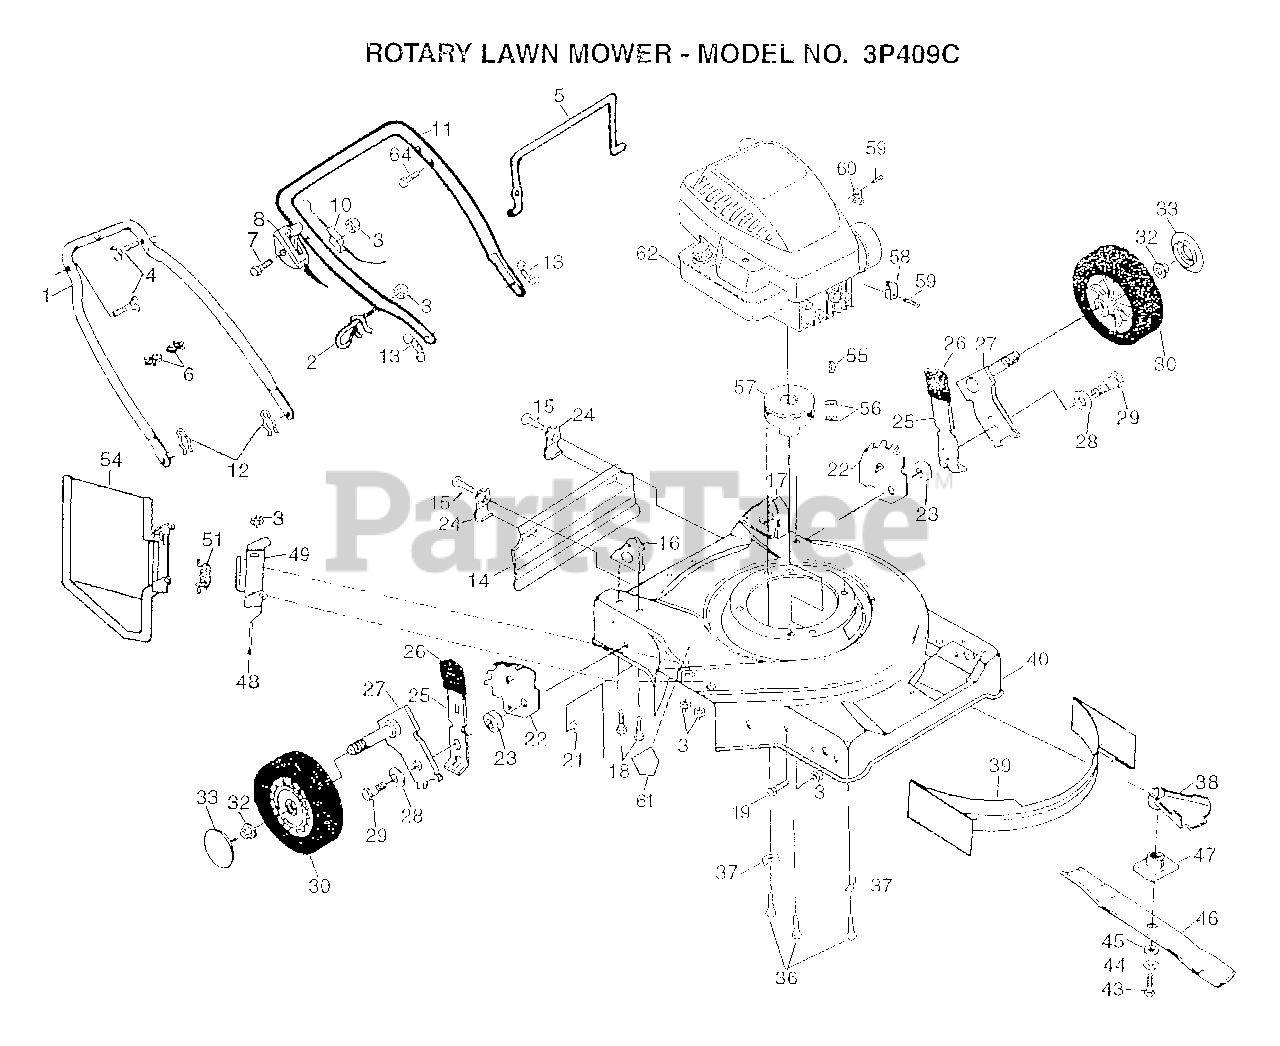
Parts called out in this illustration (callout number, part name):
1	HANDLE LOWER
2	ROPE GUIDE
4	BOLT.HANDLE.LM
5	BAIL.CNTRL.STD.BL
7	SCREW.HXHD.WASH.
8	CONTROL THROTTLE
10	"CABLE,ENG ZONE CO"
12	HAIRPIN COTTER
13	"NUT,WING PM"
14	SKIRT.REAR.FGD.22
15	TAPPING SCREW
16	HDLE BRKT ASSY.RH
17	HDLE BRKT ASSY LH
18	SCREW 5/16-18X3/4
19	SCREW
21	LOCKNUT PM
22	BRACKET.ADJ.9POS.
23	SPACER.HEIGHT.ADJ
24	"BRKT,DEFL PM"
25	SPRING SELECTOR
26	KNOB PM
27	ARM.AXLE.ASM.BZP.
28	"WASHER, BELLEVIL."
29	BOLT SHLD 3/8-16
30	WHEEL.8X2.PR.RAD.
32	HEX FLANGE LOCKNT
33	HUB CAP
36	BOLT.ENG.3/8-16
39	BAFFLE FRONT 22SD
40	KIT.HSG.22SD.FWGD
43	SCREW
44	LOCKWASHER
45	"WASHER,HARDEN"
46	"BLADE.MULCH.22"""
47	ADAPTOR.BLADE.LM
48	ROD.HINGE.COMBI-C
49	BRACKET.HINGE.W/F
51	SPRING.HINGE
54	GUARD.DISCH.22SD.
55	HI PRO KEY PM
56	SCREW
57	ENGINE.PULLEY.FWG
58	CABLE CLAMP
59	SCREW PM
60	GUIDE CLIP PM
61	DECAL HYT
